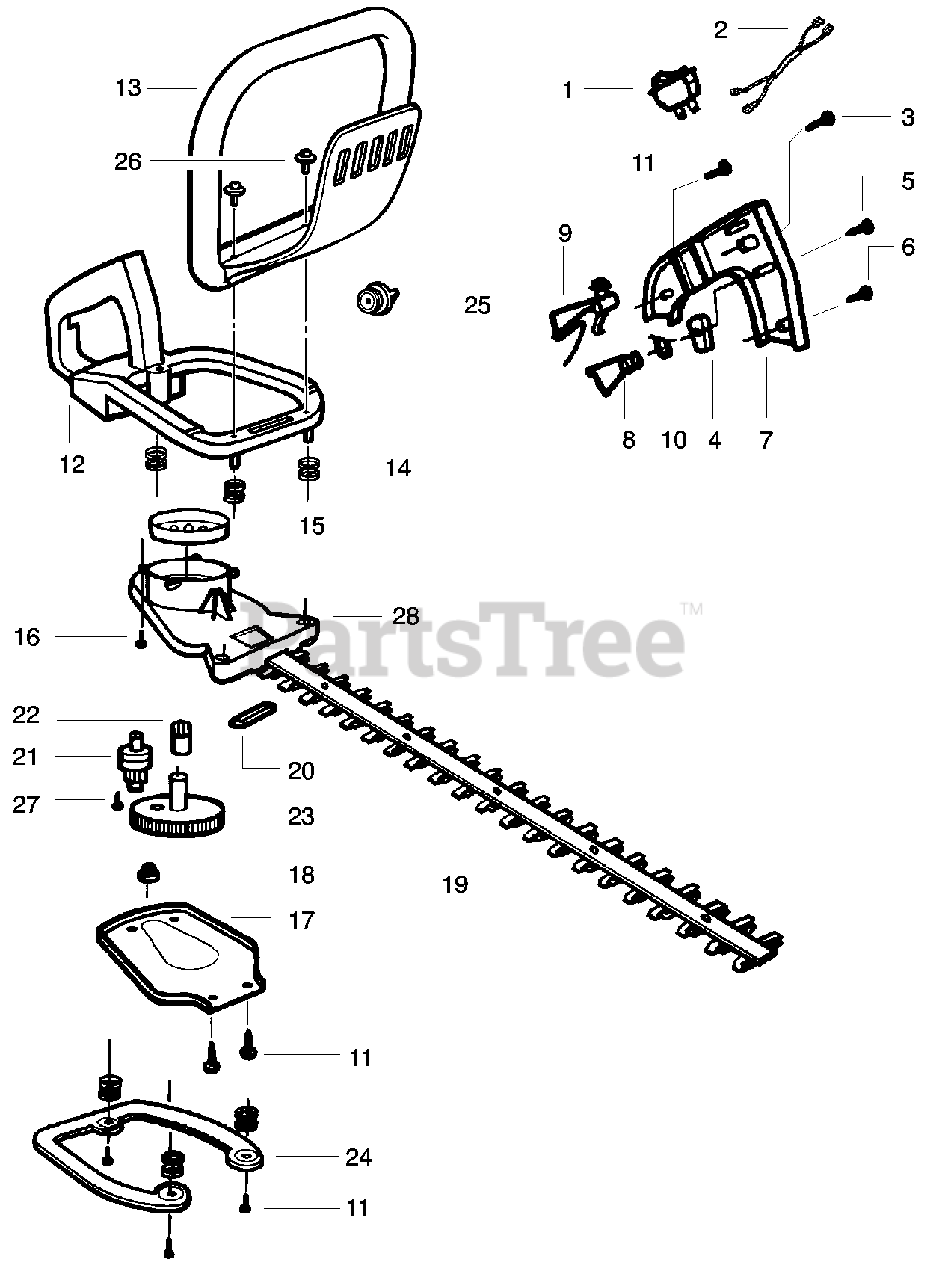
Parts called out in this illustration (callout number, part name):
1	Switch-Ignition
2	Assy-Switch Wire
4	Lever-Trigger
7	Cover-Handle
8	Trigger-Throttle
9	Lockout-Throttle
10	Spring-Trigger
12	Assy-Rear Handle/Tank
13	Handle-Front
15	Assy-Clutch & Drum
17	Plate-Gear Box
18	Bushing-Blade
19	Assy-Blade 19"
19	Assy-Blade 22"
20	Seal-Blade
21	Assy-Pinion
22	Bearing-Gear
23	Assy-Drive Gear
24	Plate-Isolator
25	Assy-Fuel Cap
27	Screw
28	Assy-Gear Box
